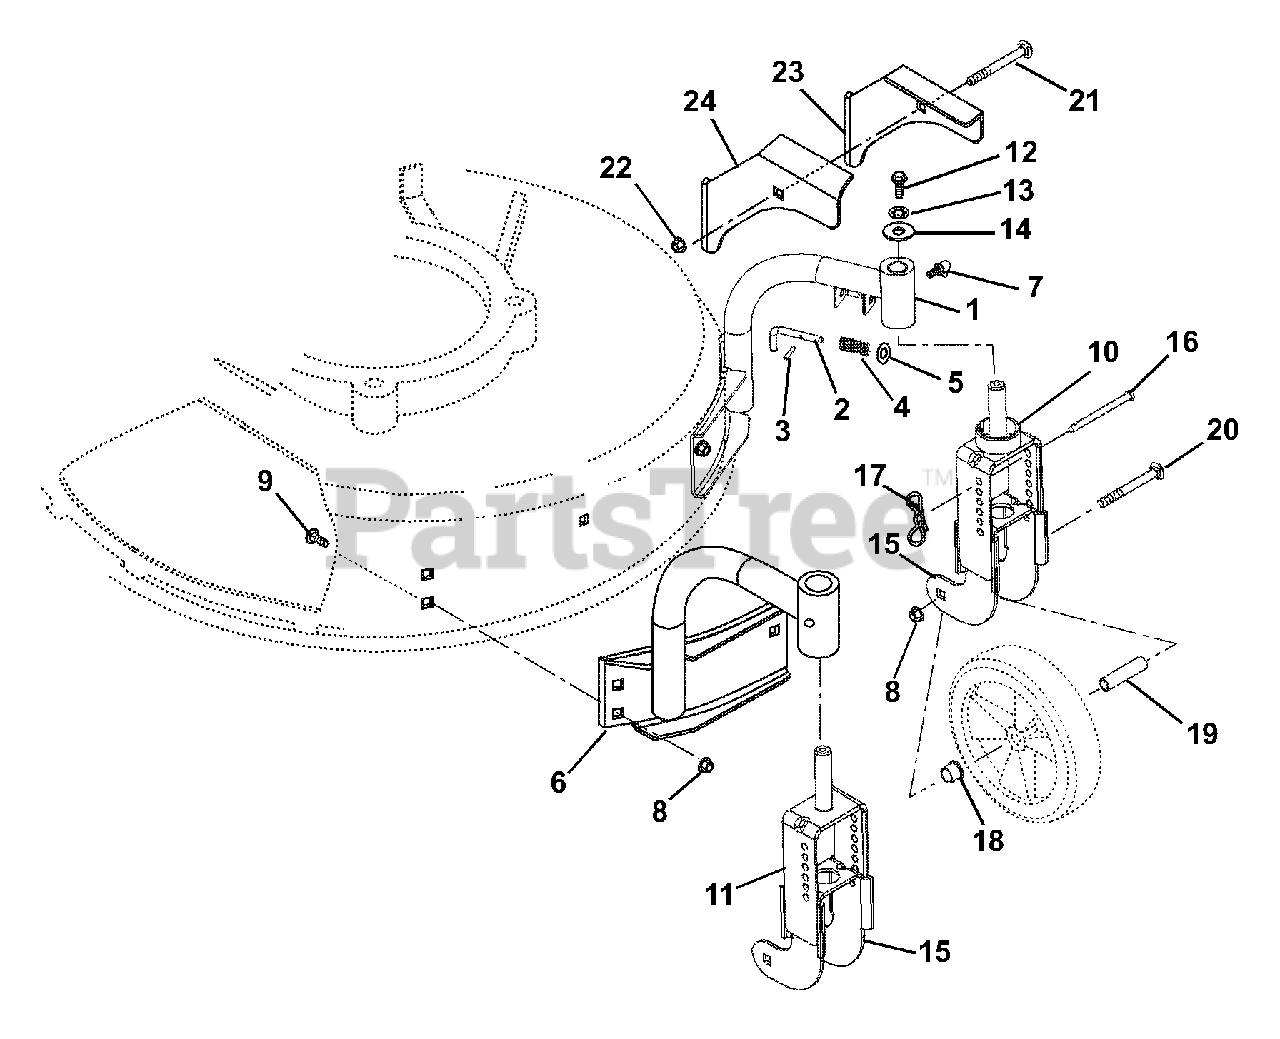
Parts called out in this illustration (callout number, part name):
1	ASSY, MOUNT LH W/BUSHINGS
2	PIN, LOCKOUT
3	PIN-ROLL .094X.750
4	SPRG, COMP--SWVL LOCKOUT
5	@WSHR-FL-STL.281X.62X.065 YWZC
6	ASSY, RH MOUNT W/BUSHINGS
7	FTG-LUBE .25-28X.256 YWZC
8	@NUT-SPNLK-FLG .312-18 YWZC
9	@BLT-RDHDSQNK .31-18X.50 G5YZ
10	YOKE, OUTER LH
11	YOKE, RH OUTER
12	@BLT-HEX .25-20X.75 GR5 YWZC
13	@WSHR-LK .25X.062 REG YWZC
14	WSHR-FL-STL .281X1.000X.063
15	YOKE-INNER
16	PIN, HEIGHT ADJUSTMENT
17	PIN, BOW TIE LOCKING COTTER
18	BSHG-FLG .500X.625X.500X.750
19	SPCR, WHEEL .385X.500X2.00
20	BLT-RDHDSQSHNK.31-18X2.75G2YWZ
21	@BLT-RDHDSQNK .25-20X1.50 G5YZ
22	@NUT-SPNLK-FLG .25-20 YWZC
23	BRACKET, HOOD CABLE--LH
24	BRACKET, HOOD CABLE WELDMENT
